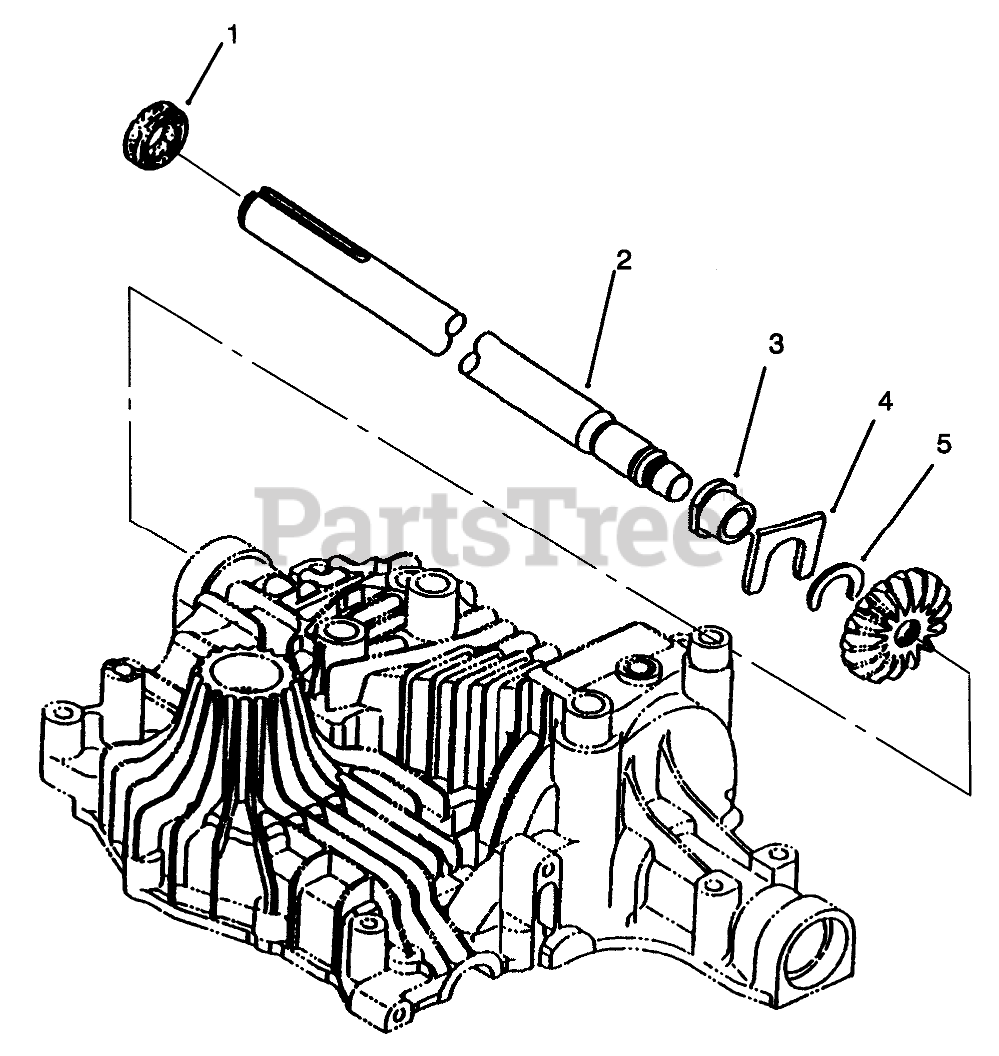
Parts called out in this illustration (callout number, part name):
2	Shaft-Axle Right
3	BUSHING
4	WASHER - THRUST
